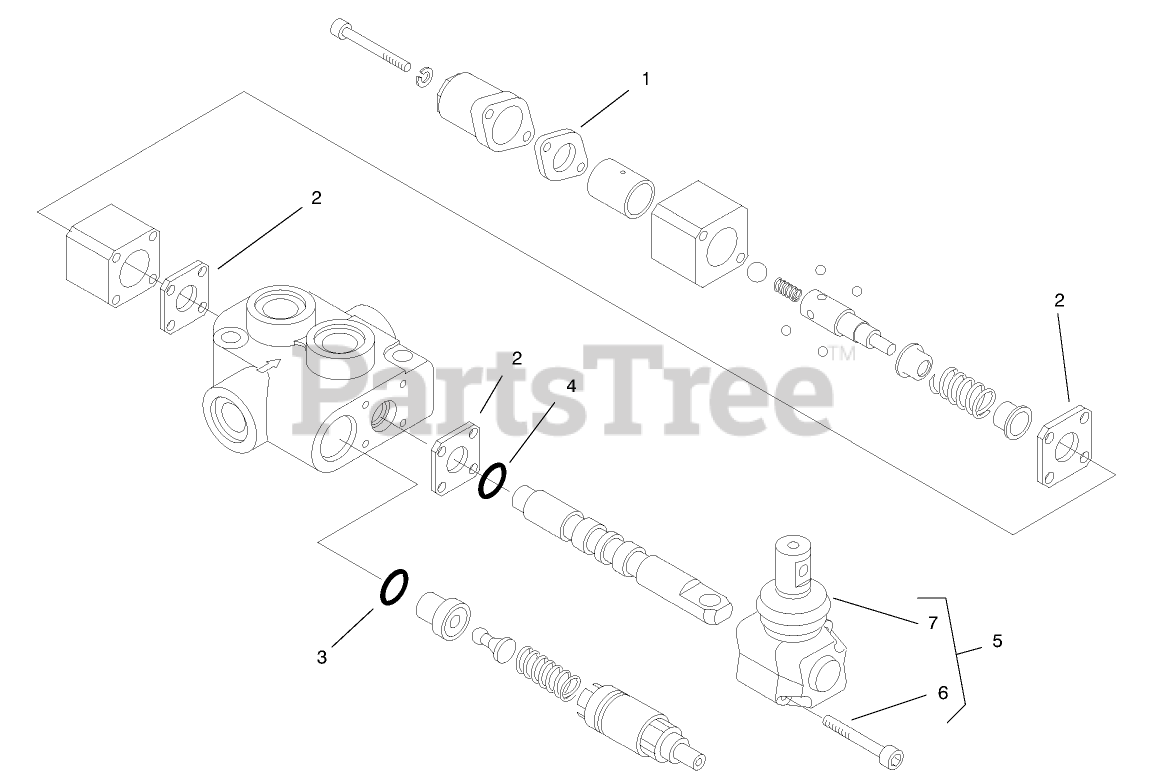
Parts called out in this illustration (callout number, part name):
1	GASKET
2	GASKET
5	OPERATOR ASM
